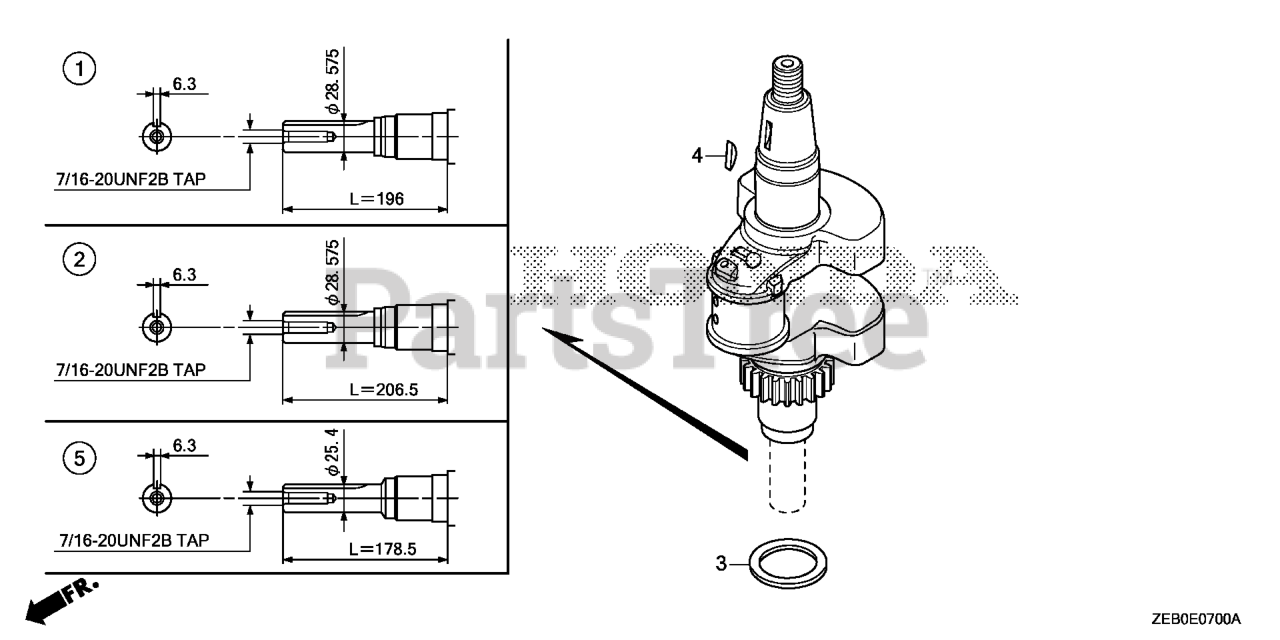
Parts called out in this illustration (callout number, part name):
2	CRANKSHAFT
3	WASHER, CRANKSHAFT THRUST
4	KEY, SPECIAL WOODRUFF (25X18)
